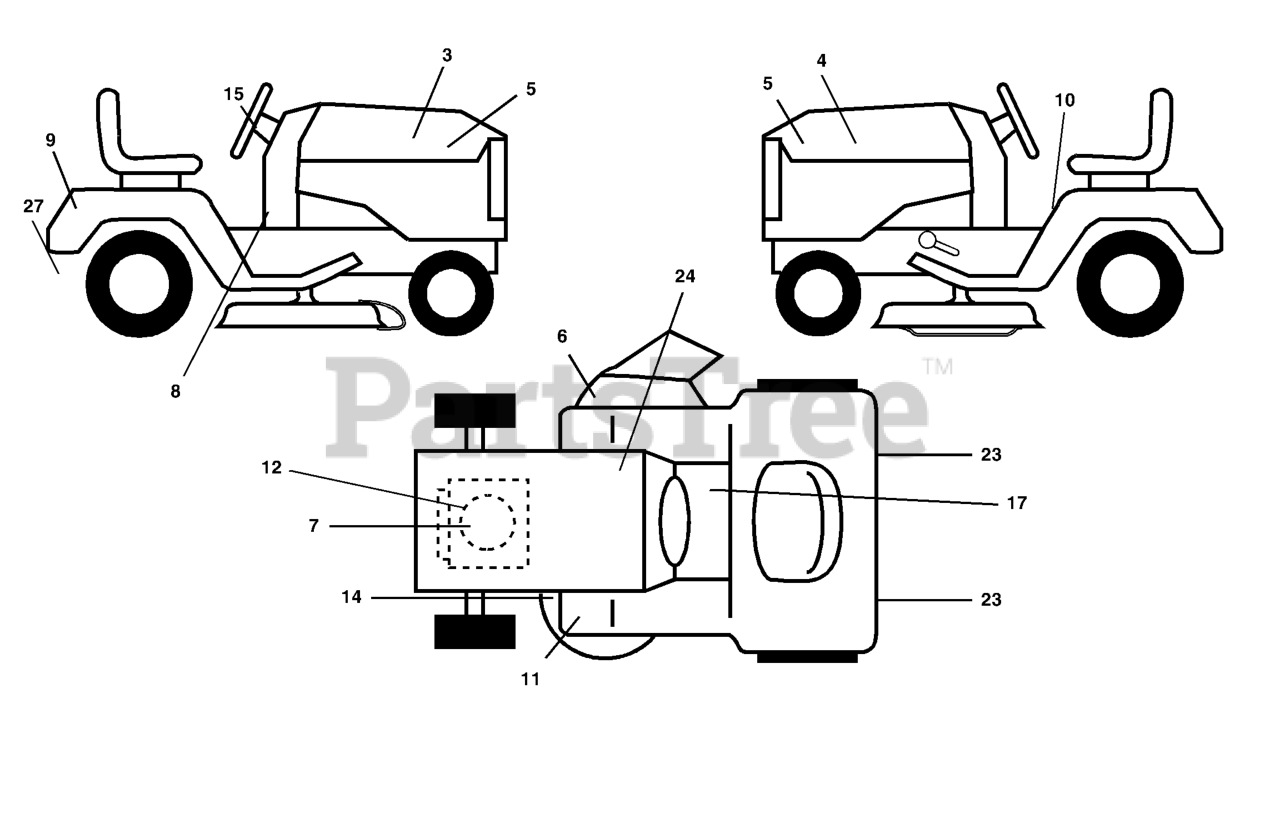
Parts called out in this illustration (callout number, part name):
3	HOOD DECAL RH
4	DECAL HOOD LH
5	DECAL, HOOD SIDE
6	DECAL.WARN.KEEP.HAND.AWAY
7	DECAL, ENGINE HP
8	DECAL, DASH
9	DECAL, FENDER
10	DECAL FENDER DANGER
11	DECAL, CLUTCH/BRAKE
12	DECAL, ENGINE LOGO
14	DECAL V-BELT SCHEMATIC
15	DECAL.WHEEL.STEERING.HUSQ.PERM
17	DECAL PARK BRAKE
23	REFLECTOR-TAIL YT
24	DECAL BTRY SYMBOLS
27	DECAL.BYPASS.FENDER.CRD.LT.YT
